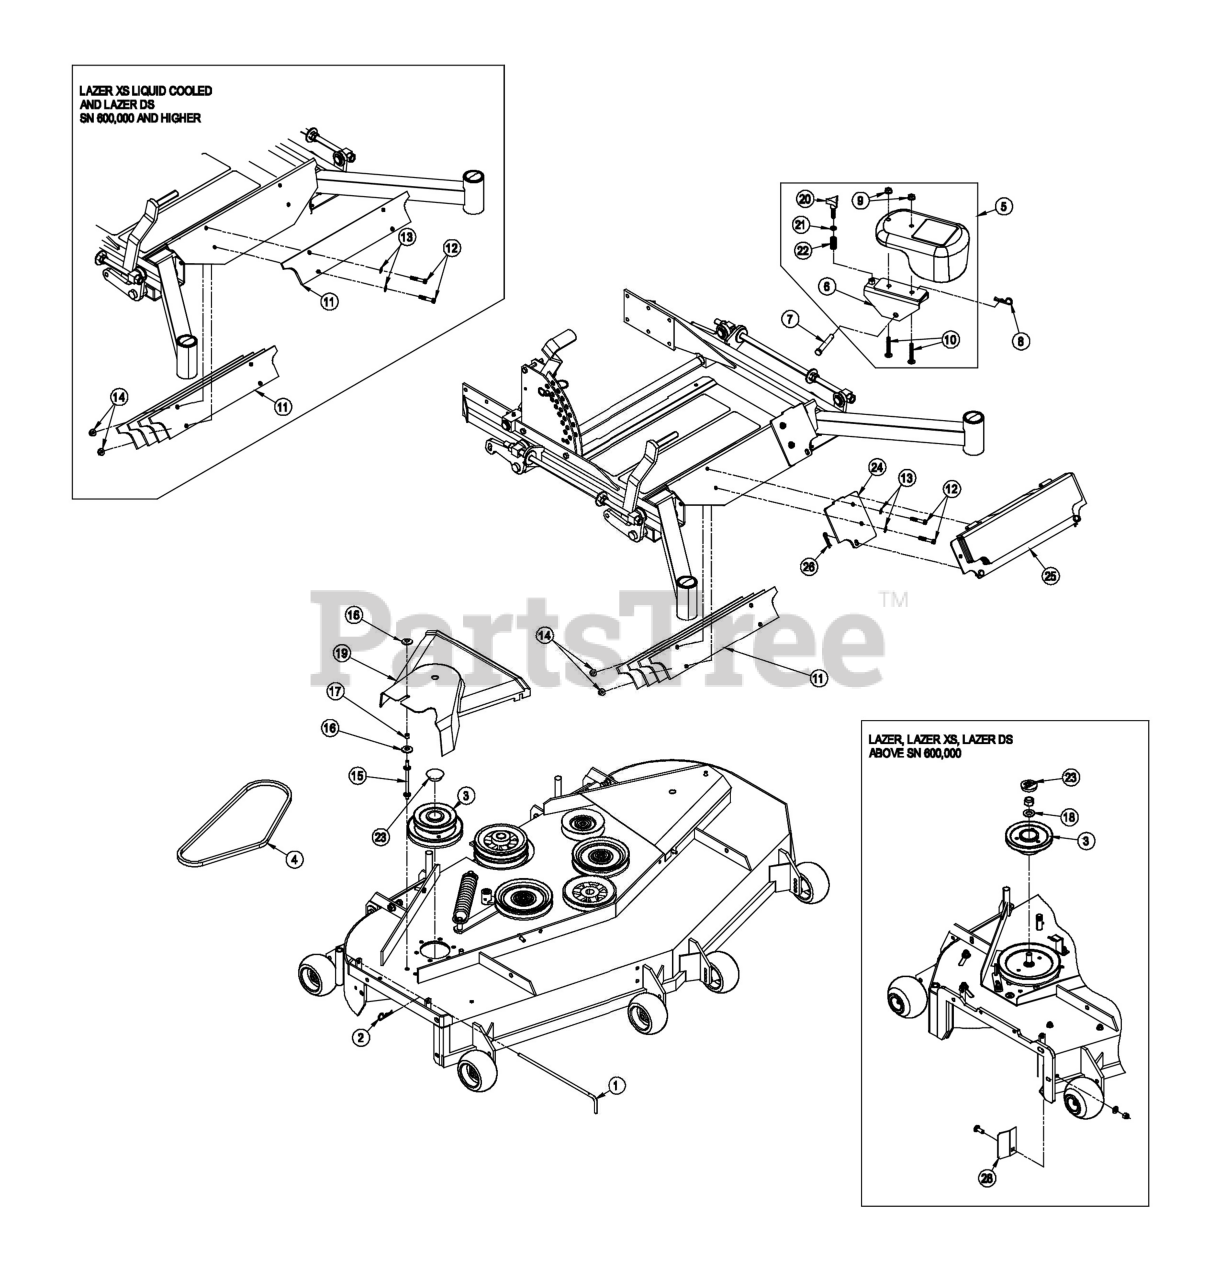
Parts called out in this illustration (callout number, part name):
1	PIN,CHUTE PIVOT
2	PIN-COTTER
3	JACKSHAFT, LZUV72
4	BELT, BLOWER DRIVE 72
5	ASM, WEIGHT 2.0" 43 POUND
6	WLD, BRACKET 2.0 ARM
7	PIN-CLEVIS
8	PIN-COTTER
9	NUT-HHF, WHIZ
10	BOLT-SQH
11	PLATE, WEIGHT
12	SCREW-HH
13	WASHER-PLAIN
15	STUD,BELT SHIELD 4 INCH
19	COVER, BELT 72
21	WASHER-FLAT
23	PLUG, BLACK NYLON 1.75
24	PLATE, WEIGHT MOUNTING
25	ASM, WEIGHT PLATE WITH DE
26	PIN-HAIR
